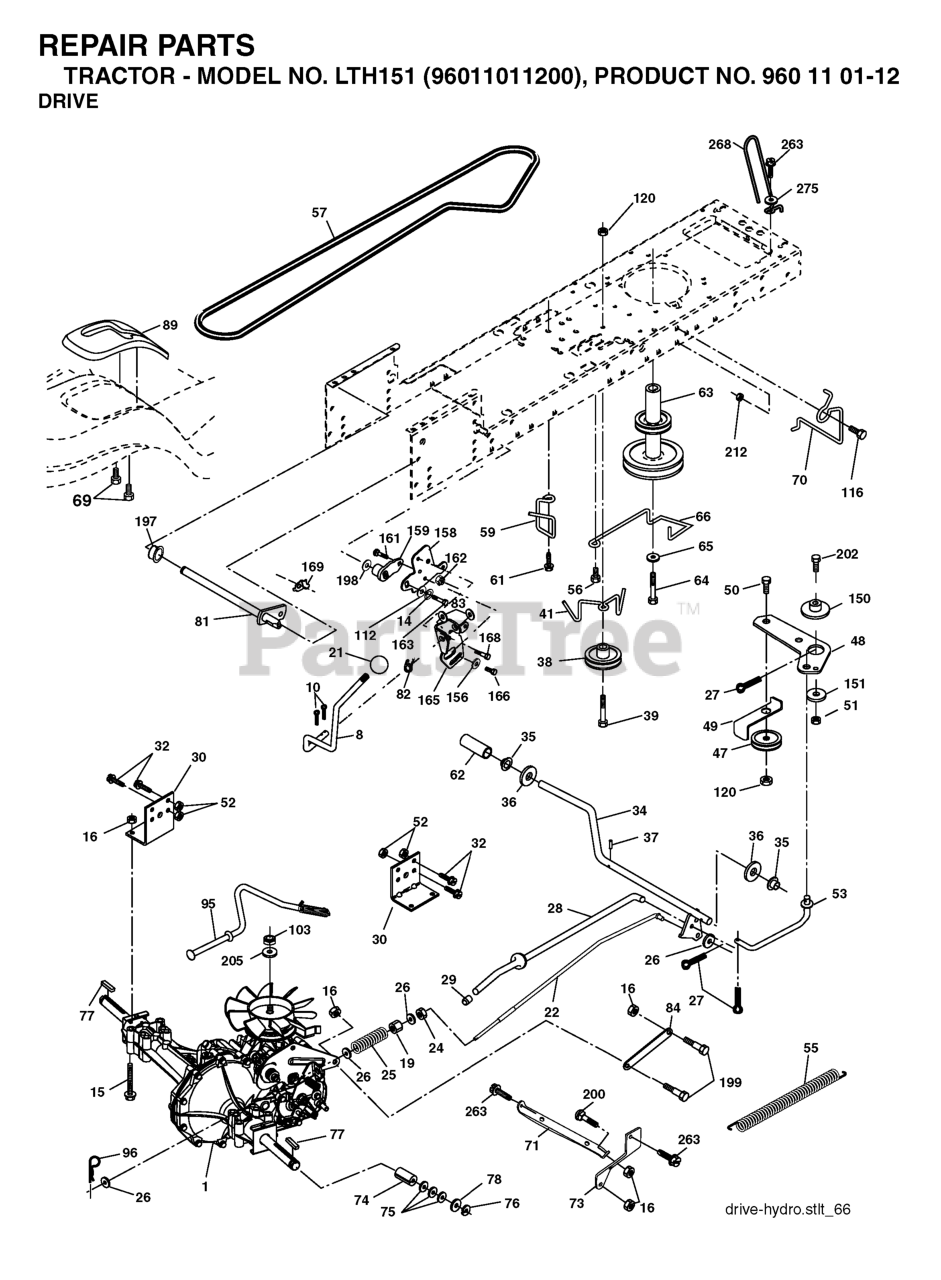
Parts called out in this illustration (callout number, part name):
8	ROD.SHIFT.FENDER.ADJ.STLT
10	PIN COTTER
14	LOCKWASHER
15	BOLT HEX 5/16-18 GR 5
16	NUT.71038.31-18.HEX.NYLOCK
19	NUT
21	KNOB.DUCKHEAD.1/2
22	ROD BRAKE HYDRO
24	NUT
25	SPRING ROD LT
26	WASHER
27	COTTER PIN
28	ROD, PARKING BRAKE
29	PLUNGER CAP
30	BRKT, MOUNT TRNSAXLE
32	BOLT
34	SHAFT, FOOT PEDAL
35	BEARING.NYLON
37	DRIVE PIN
38	PULLEY IDLER COMPOSITE
41	KEEPER, BELT IDLER
47	IDLER PULLEY
48	BELLCRANK, CLUTCH
49	RETAIN BELT
50	BOLT.3/8-16X1.50
52	LOCKNUT
53	LINK.CLUTCH.7.66.2005
55	SPRING, RETURN LT
56	SCREW.3/8-16
57	DRIVE BELT, LTH & YTH TRACTORS
59	KEEPER, BELT CENTER
61	SCREW 3/8-16X.875
62	PEDAL COVER T
63	ENGINE PULLEY
64	BOLT HEX 7/16-20X4-1/4"
65	LOCKWASHER
66	KEEPER BELT ENGINE
69	SCREW.HI-LO.CONSOLE
70	KEEPER BELT ENG
71	STRAP TORQUE LH HYDRO
73	STRAP TORQUE RH HYDRO
74	SPACER AXLE
77	SQUARE KEY
81	SHAFT ASM CROSS TAPERED
82	SHIFT SPRING
83	WASHER
84	LINK TRANSAXLE
89	CONSOLE, SHIFT, STL, AUTO GREY
95	CONTROL ASM. BYPASS HYDRO
96	RETAINER M
103	NUT.HEX.1/2-20
116	BOLT D
120	NUT LOCK FLG 3/8-16 UNC
150	SPACER, RETAINER
151	WASHER 12/32X2X10GA
156	WASHER.SRRTD.5/16
158	BRACKET
159	RB HUB.SHIFT
161	BOLT
162	NUT.CROWNLOCK.1/4
165	RP BRACKET
166	CAPSCREW.HXHD.FLG.5/16-18X.625
168	BOLT.SHOULDER.5/16-18X
169	PLATE.FASTENING.CROSS.SHAFT
197	NYLINER SNAP 5/8" ID
198	WASHER.NYL.7/8IDX.105"HYD CR
199	BOLT SHOULDER 5/16-18 UNC
205	WASHER
212	NUT
263	SCREW, 3/8-16X3/4
268	GUARD MUFFLER
275	WASHER
